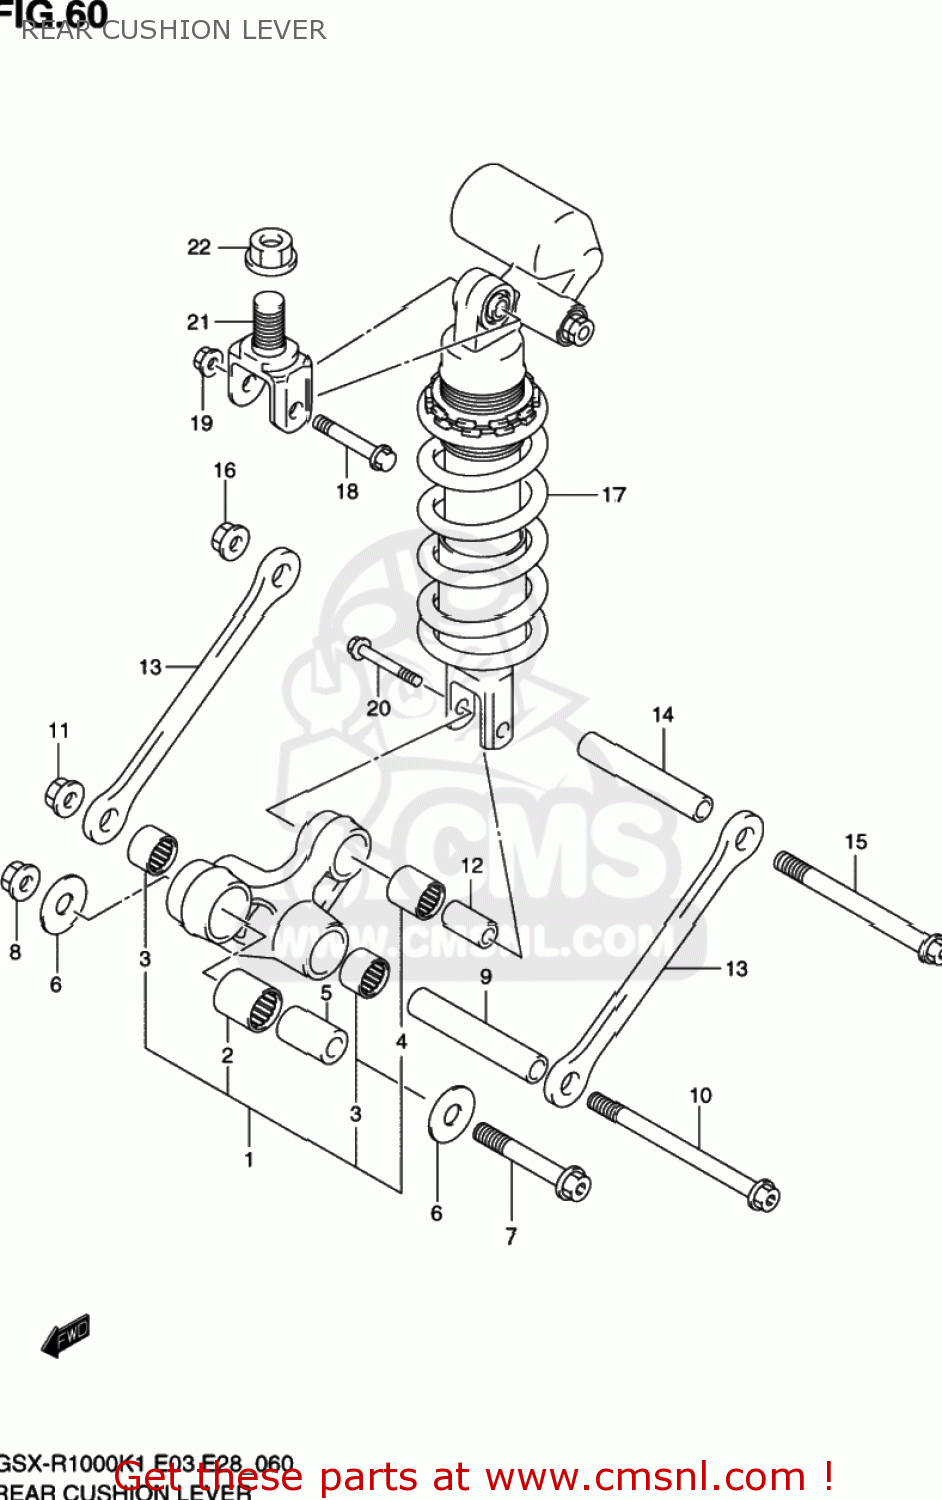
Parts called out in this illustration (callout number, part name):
1	LEVER SET,REAR CUSHION
2	BEARING(20X27X30)
3	BEARING(17X24X20)
4	BEARING(17X24X26)
5	SPACER,RR CUSHION LEVER FR
6	WASHER(12X34X1)
7	BOLT,RR CUSHION LEVER FR
8	NUT 12MM
9	SPACER,RR CUSHION LEVER CTR
10	BOLT,RR CUSHION LEVER CTR
11	NUT 12MM
12	SPACER,RR CUSHION LEVER
13	ROD,RR CUSHION
14	SPACER,RR CUSHION LEVER CTR
15	BOLT,RR CUSHION LEVER CTR
16	NUT 12MM
17	ABSORBER ASSY,RR SHOCK
18	BOLT(10X55)
19	NUT
20	BOLT(10X55)
21	BRACKET,RR SHOCK ABSORBER UPR
22	NUT
